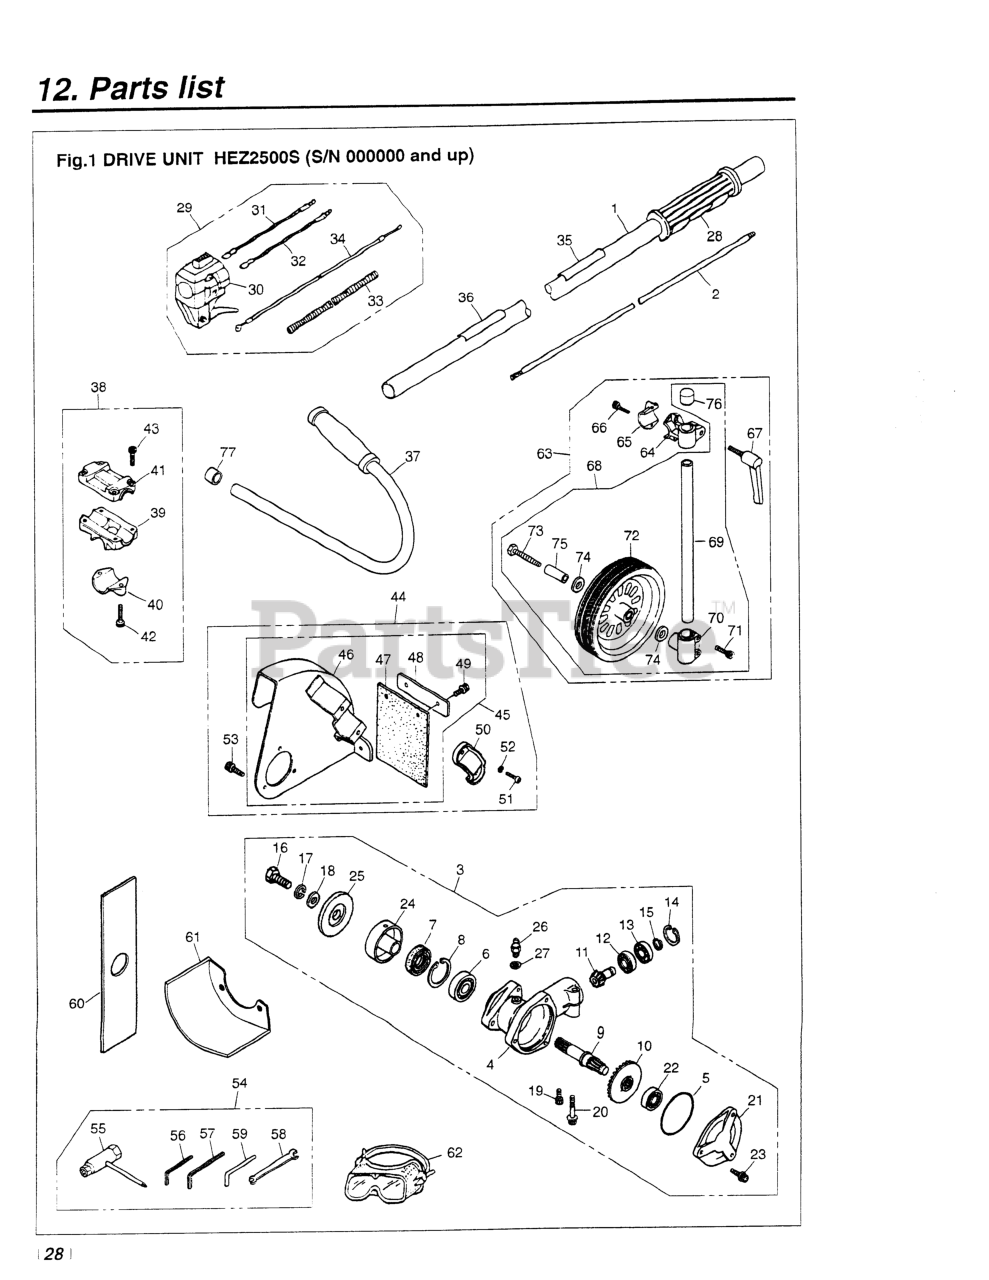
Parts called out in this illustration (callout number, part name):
1	PIPE COMP
5	O-RING
7	SEAL, OIL
8	RING, SNAP, M32 x 1.2
9	SHAFT, GEAR
10	GEAR
11	PINION
12	BEARING (RPLS T3403-13530)
13	BEARING (RPLS T3300-13531)
14	RING, SNAP, M24 x 1.2
15	RING, SNAP (RPLS T3300-13330)
16	BOLT, LH
17	WASHER (RPLS 3180-13270)
18	WASHER, M8 x 2.3 (RPLS -20823)
19	BOLT, M5 x 12
20	BOLT, M6 x 1.35
21	COVER
22	BEARING (RPLS T3403-13510)
23	BOLT
24	HOLDER (A)
25	HOLDER (B)
26	FITTING, GREASE
27	WASHER, M6 X .8
28	GRIP (RPLS 3577-32140 & 3220-
31	CORD (A), BLACK
32	CORD (B), RED
33	TUBE (RPLS 4900-72141)
34	CABLE (RPLS 5580-83100)
35	PLATE, NAME (HEZ2500S)
36	PLATE, CAUTION
37	HANDLE, J
38	BRACKET ASSY (REPLACES -14100)
40	CAP, LOWER
41	CAP, UPPER (RPLS -14191)
42	BOLT, M5 X 22
43	BOLT, M5 X 25
47	PLATE (RUBBER)
48	PLATE (REPLACES -24130)
49	BOLT, M5 X 12
51	BOLT, M6 X 18
52	WASHER, M6 X 15
53	BOLT
55	SOCKET
56	WRENCH (TOOL)
57	WRENCH (TOOL)
58	SPANNER, 8 X 10 (RPLS 2540- )
59	BAR
60	BLADE, EDGER (RPLS 147315)
61	COVER (CAN USE 6367-96110)
62	GOGGLE
63	WHEEL ASSY COMP (RPLS -25000)
64	BRACKET
65	CAP, LOWER
66	BOLT, M5 X 22
67	LEVER
68	WHEEL ASSY (RPLS -25100)
69	PIPE
71	BOLT, M6 X 25
72	WHEEL
73	BOLT (REPLACES -81060)
74	WASHER, M10 x 1.6
75	SPACER, PIPE
76	CAP
77	CAP
